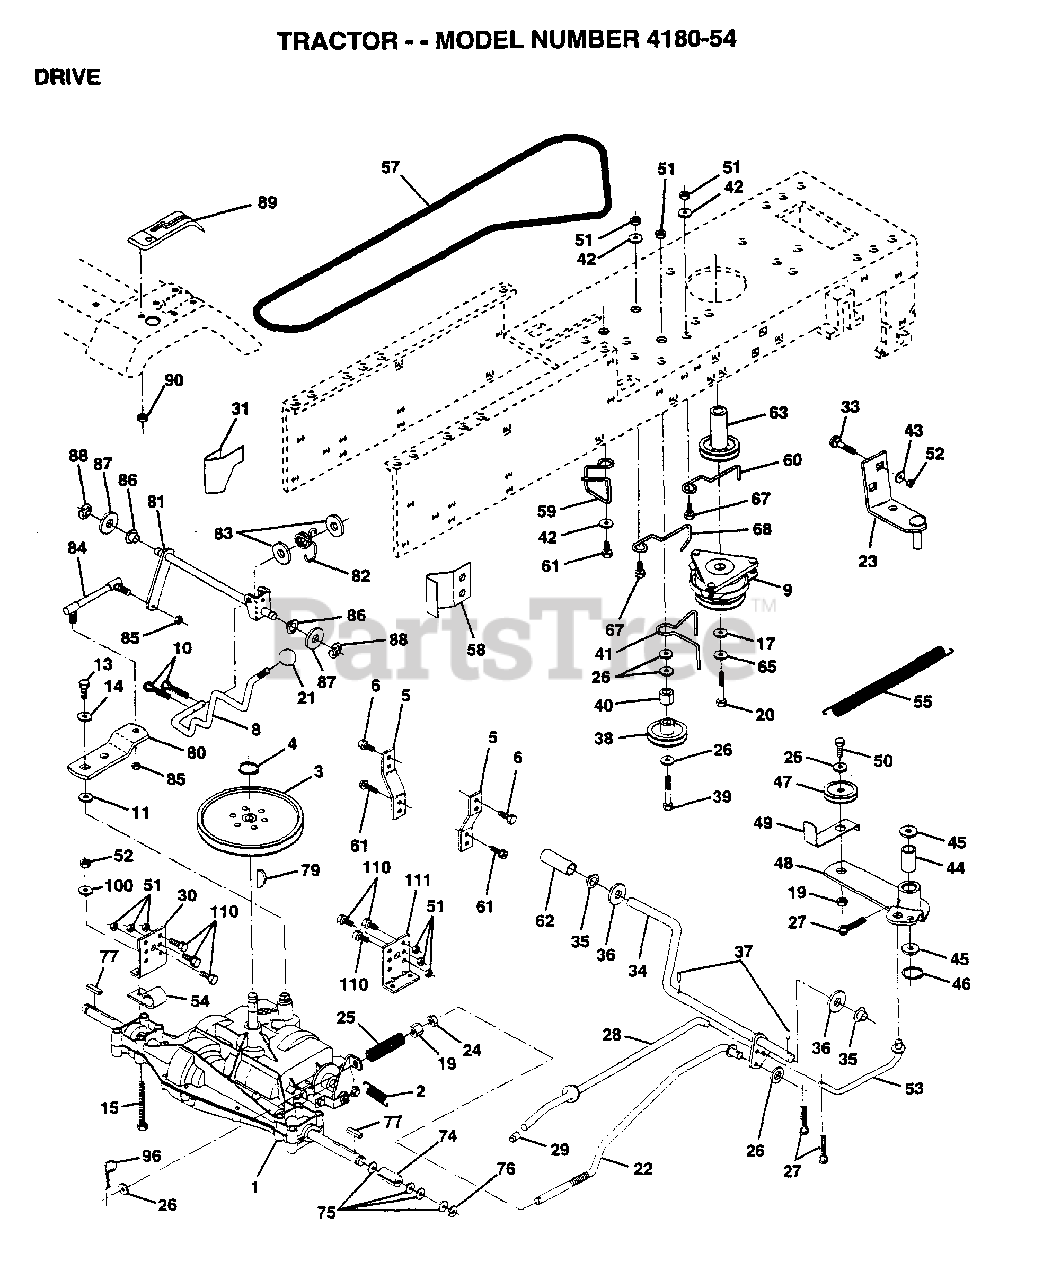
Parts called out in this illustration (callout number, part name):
1	TRANSAX. PRLES.
3	PULLEY TRANSAXLE
4	RING
5	STRAP TORQUE
6	SCREW
10	PIN COTTER 1/8
11	WASH-SHFT PLT LT
13	BOLT.1/4-28.W/PAT
14	WASHER PM
15	BOLT HEX
17	WASHER
19	NUT
21	KNOB T (1/2-HOLE)
22	ROD.ASM.BK.44.MWR
23	BRACKET.ASM.MTG
24	NUT
25	"SPRING,ROD BRAKE"
26	WASHER
27	COTTER PIN
28	ROD.BRAKE.PARK.LT
29	PLUNGER CAP T
30	BRKT TRANS LH
31	KEEPER BELT LH
33	BOLT
35	NYLON BEARING
36	WASHER LT
38	PULLEY.IDLER.FLAT
39	BOLT
40	SPACER T
41	BELT KEEPER LT
42	WASHER
43	WASHER T
44	"LY, BEARING"
45	WASHER LT
46	KLIP RING
48	ARM IDLER
49	RETAIN BELT
53	"LINK, CLUTCH T"
54	"CLIP,INSULATOR"
55	"SPRING, RETURN LT"
57	BELT.GRDRV.94.75
58	"KEEPER,BELT RH"
59	KEEPER BELT CNTSP
60	KEEPER BELT ENGLH
61	SCREW
62	PEDAL COVER T
63	PULLEY ENGINE
65	LOCKWASHER
67	BOLT
68	"KEEPER,BLT ENG LT"
74	SPACER HYT
75	WASHER
76	E RING HYT
77	SQ KEY STD
80	"ARM,SHIFT"
81	"SHAFT,SHIFTER"
82	"SPRING,TORSION"
83	WASHER
84	"ROD,TIE "
85	NUT 1/4-28
86	BUSHING
87	WASHER D
88	KLIP RING
89	CONSOLE SHIFTER
90	NUT
96	RETAINER M
100	WASHER M
111	BRKT TRANS RH
